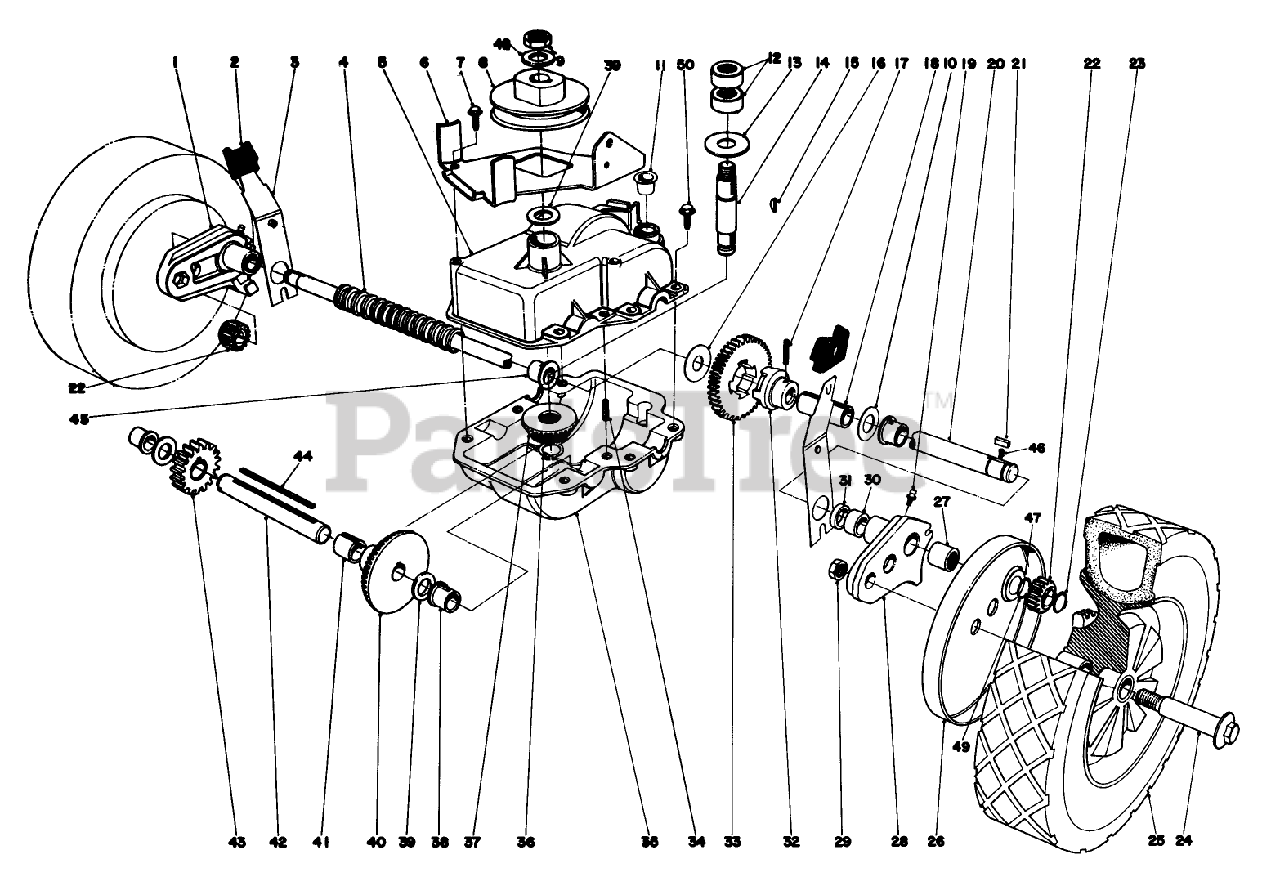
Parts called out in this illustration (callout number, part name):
1	Pivot Arm R.H. (Incl. Ref #19, 27 & 30-31)
2	KNOB-ARM
3	SP SPRING ARM ASM
4	Cover Drive Shaft
5	Case Upper
6	Bracket-Belt Guide
7	Screw
8	PULLEY
9	Nut
10	WASHER-PLAIN
11	Caplug
12	Bearing
13	Thrust Washer
14	INPUT SHAFT
15	KEY-WOODRUFF
16	WASHER
17	COIL PIN
18	Spacer-Output Shaft
19	FITTING-GREASE
20	Output Shaft
21	Key-Rectangular
22	GEAR-PINION
23	RING-RETAINING
24	BOLT-WHEEL
25	Wheel & Tire Assembly
26	Cover-Wheel
27	Needle Baring
28	Pivot Arm L.H. (Incl. Ref. #19, 27 & 30-31)
29	Nut
30	Bushing
31	Seal
32	ADAPTER DRIVE
33	Gear
34	ROLL PIN 3/16 X 1 IN
35	LOWER GEAR CASE CAST
36	RING-RETAINING
37	PINION-BEVEL
38	Botching Shaft
39	WASHER-THRUST
40	BEVEL GEAR
41	Shaft-Pivot
42	Sort Shaft
43	14 T GEAR
44	Key Square
45	Bushing
46	SPRING-COMPRESSION
47	Washer
48	WASHER-FLAT
49	RING-EXT GRIP
50	SCREW-HWH, THREAD ROLL
